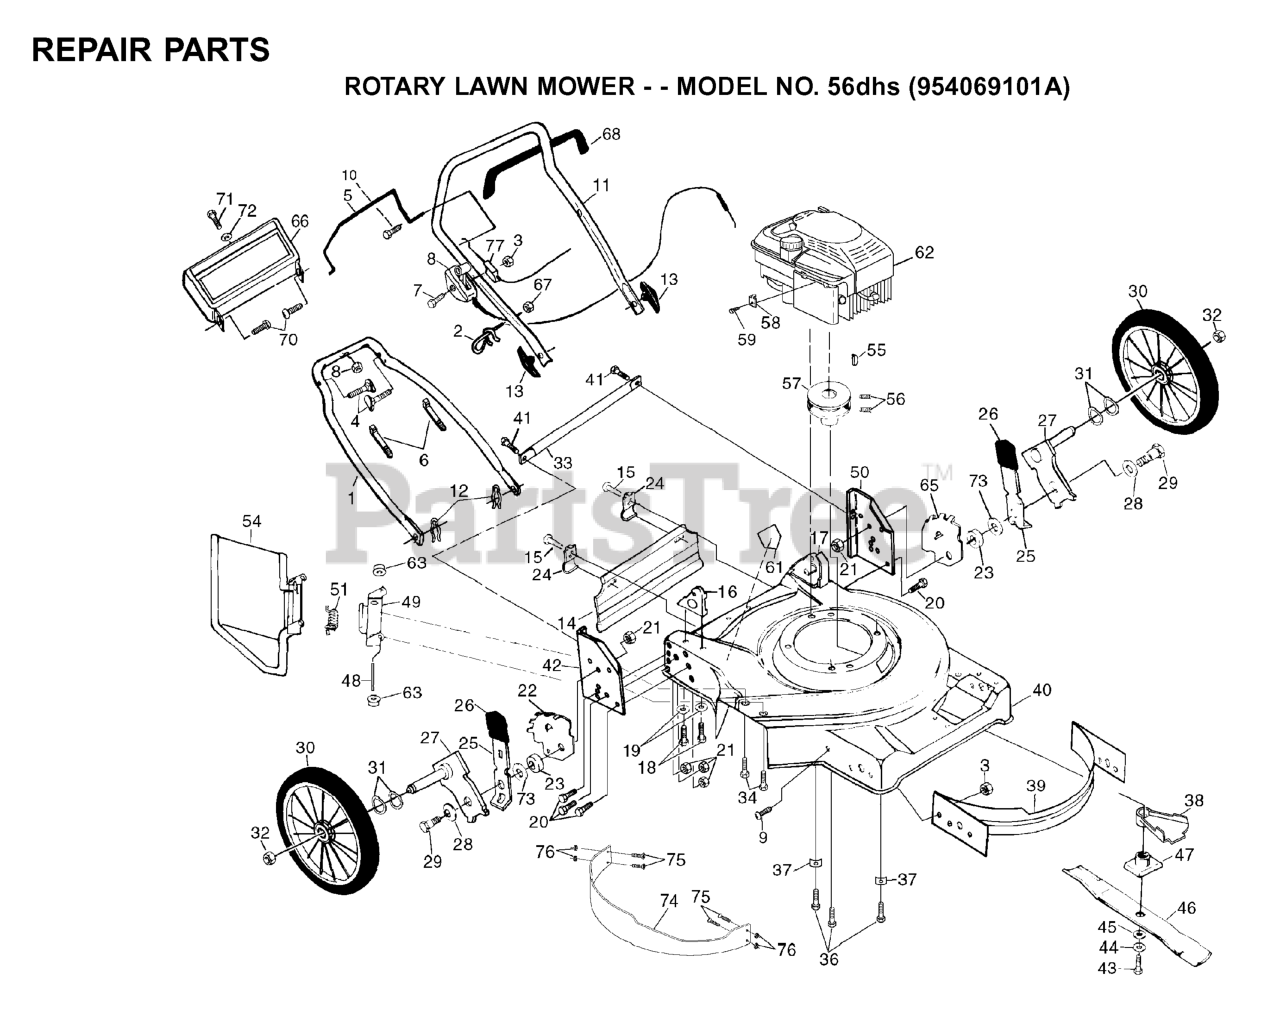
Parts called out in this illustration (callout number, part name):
1	HANDLE, LOWER PM
2	ROPE GUIDE
3	NUT
4	HANDLE BOLT
6	TIE GUIDE
7	SCREW 1/4-20 X 2.12
8	THROTTLE CONTROL
10	SELF-TAPPING SCREW
11	UPPER HANDLE
12	HAIRPIN COTTER
13	HANDLE KNOB
14	REAR SKIRT
15	TAPPING SCREW
16	HANDLE BRKT ASSY RH
17	HANDLE BRKT ASSY LH
18	SCREW
19	STEEL WASHER
21	LOCKNUT PM
22	WHL ADJ BRKT LF/RR
23	SPACER PM
24	BRACKET DEFL PM
25	SELECTOR SPRING
26	SELECTOR KNOB
29	BOLT
30	WHEEL TIRE PM
31	WAVE WASHER
32	HEX FLANGE LOCKNT
33	ROD SUPPORT
34	SCREW
36	BOLT
37	WASHER.ENGINE.BZP
38	DEBRIS SHIELD
39	FRONT BAFFLE
43	SCREW, HEX HD 3/8-24 X 1-3/8
44	LOCKWASHER
45	WASHER,HARDEN
47	BLADE ADAPTOR
48	ROD HINGE
49	BRKT HSG
51	SPRING TENSION
55	HI PRO KEY PM WSL
57	ENGINE.PULLEY.FWG
59	SCREW.HEX.HEAD.WASHER.10-16
61	DECAL HYT
63	PUSH-ON SPEED NUT
65	WHL ADJ BRKT RF/LR
67	NUT
68	HANDLE GRIP
71	SCREW
73	WASHER.FLAT.1/2
77	CABLE.MZR.51.RT.SP./PU.
